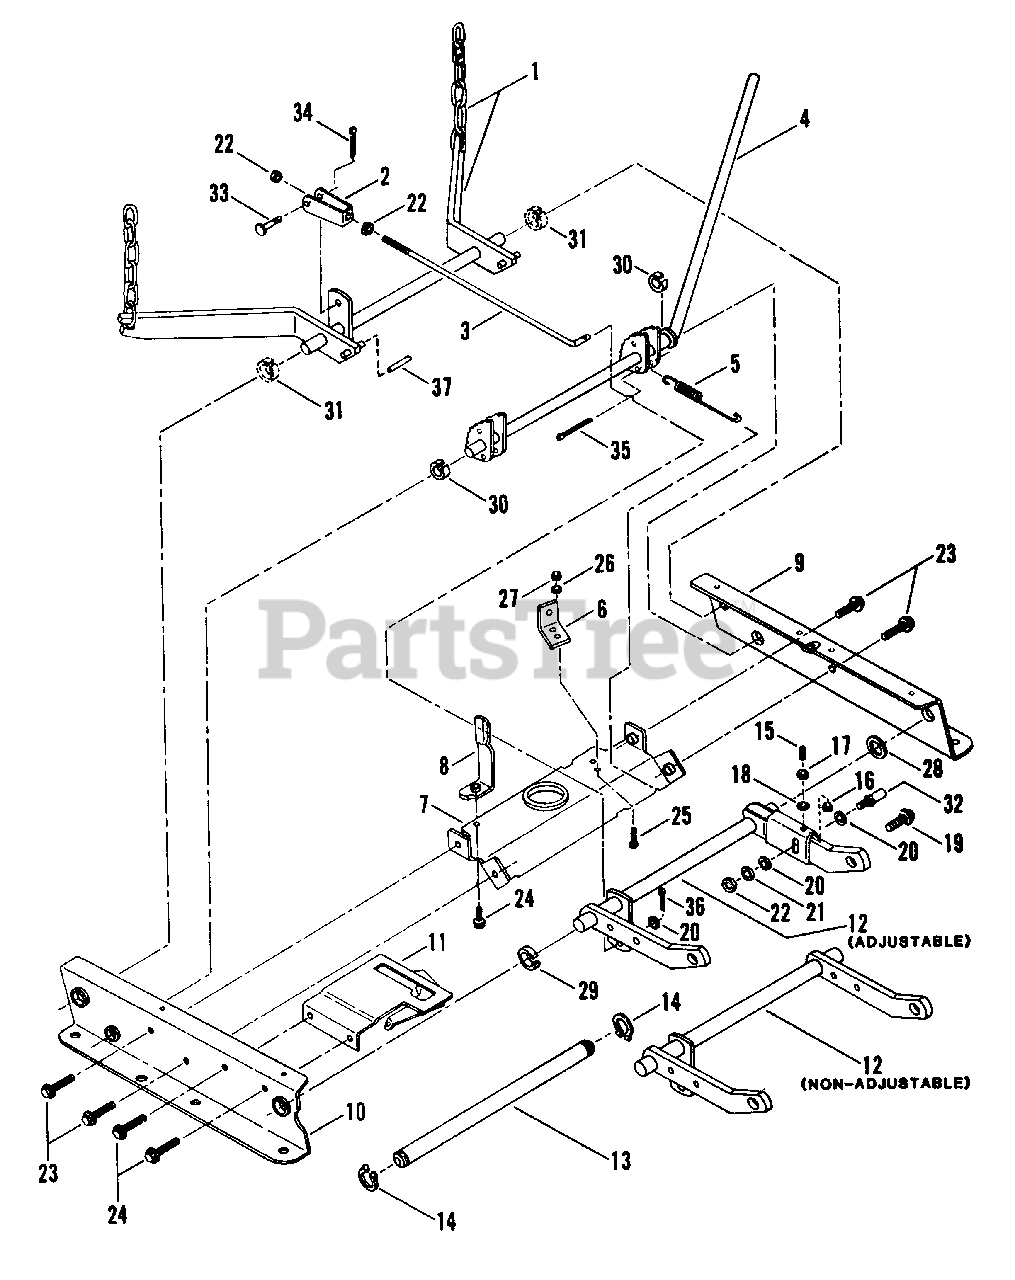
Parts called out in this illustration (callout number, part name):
1	REAR LIFT ARM ASSY
2	CLEVIS, Timing Rod
3	TIMING ROD
4	CAM LIFT LEVER
5	SPRING, Cam Lift
6	ANCHOR
7	BRACE, Top
8	GUIDE, Belt
9	RAIL, Left Hand
10	RAIL, Right Hand
11	CLUTCH-PLATE
12	FRONT LIFT ARM
13	SUPPORT ROD
14	RING, 5/8" External Retaining
15	SETSCREW, 5/16-18x1-1/4 Hex Socket
16	NUT, 5/16-18 Hex
17	JAM-NUT, 5/16-18 Hex
18	WASHER, 5/16 SAE
19	CAPSCREW, 3/8-24x1-1/4 Hex Head
20	WASHER, 3/8 SAE
21	LOCKWASHER, 3/8 Split
22	NUT, 3/8-24 Hex
23	SCREW, 3/8-16x1 Hex Self-Tap
24	SCREW, 5/16-18x5/8 Hex Self-Tap
25	SCREW, 5/16Fx3/4 Hex Head Cap
26	LOCKWASHER, 5/16 Internal Tooth
27	NUT, 5/16-24 Hex
28	WASHER
29	RING, Red (.36" wide)
30	RING, White
31	RING, Blue (.665" wide)
32	PIN, Shoulder Bolt
33	PIN, 3/8 x 1 1/16" Clevis
34	PIN, 3/32x3/4 Cotter
35	PIN, 5/32x1 Cotter
36	PIN, 1/8x3/4 Cotter
37	PIN, Roll
